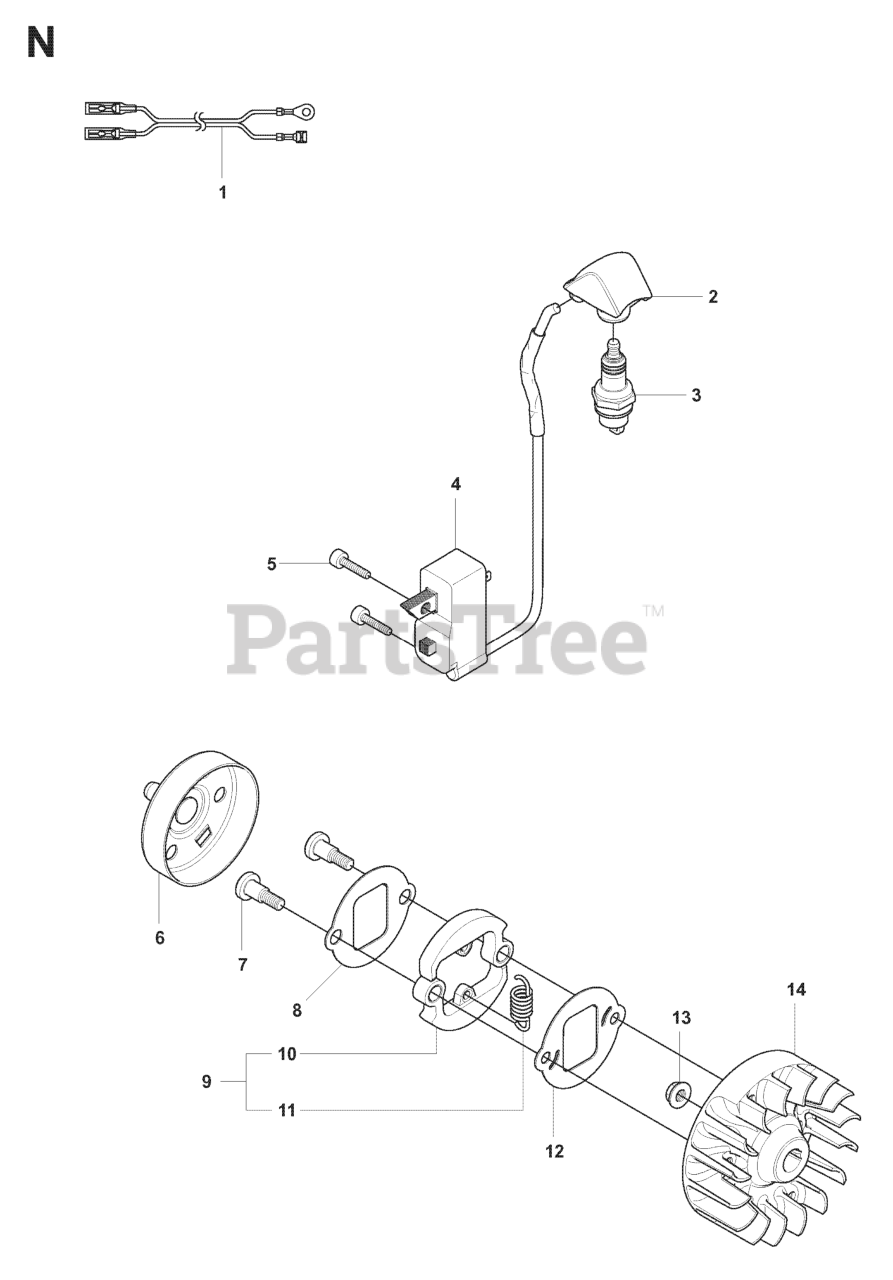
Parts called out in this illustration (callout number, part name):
1	SHORT CIRCUIT CABLE
2	SPARK PLUG CAP
3	SPARK PLUG RCJ6Y NLA
4	IGNITION MODULE
6	CLUTCH DRUM
8	WASHER, CLUTCH
13	FLANGE NUT
